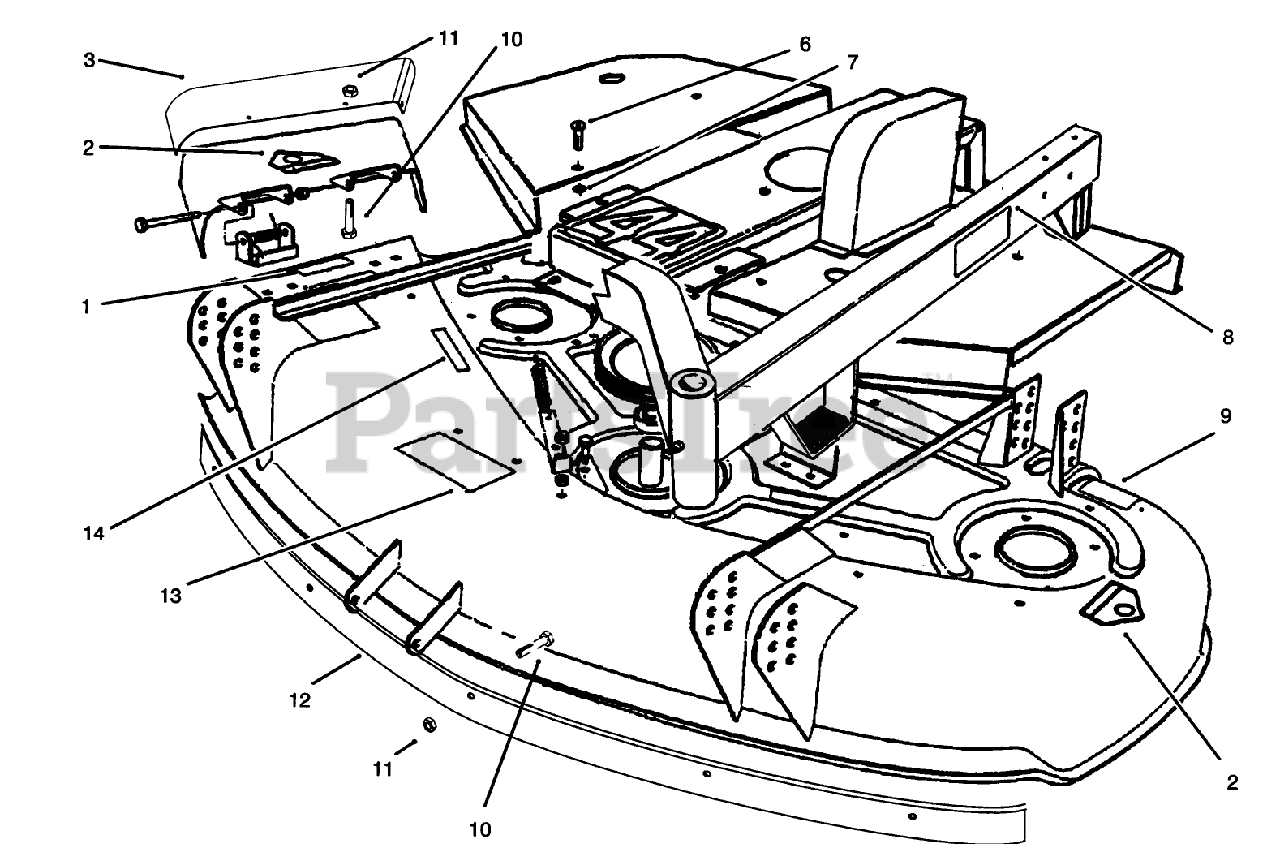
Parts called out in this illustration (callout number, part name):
1	DECAL-DANGER
2	DECAL-DANGER
3	Guard-Deflector
6	FASTENER-1/4 TURN
7	RING-SNAP
8	DECAL-HOC
9	DECAL-TORQUE, BLADE BOLT
10	SCREW-HH
11	NUT-LOCK, NI
12	Baffle-Front
13	DECAL - WARNING
14	DECAL-DANGER
